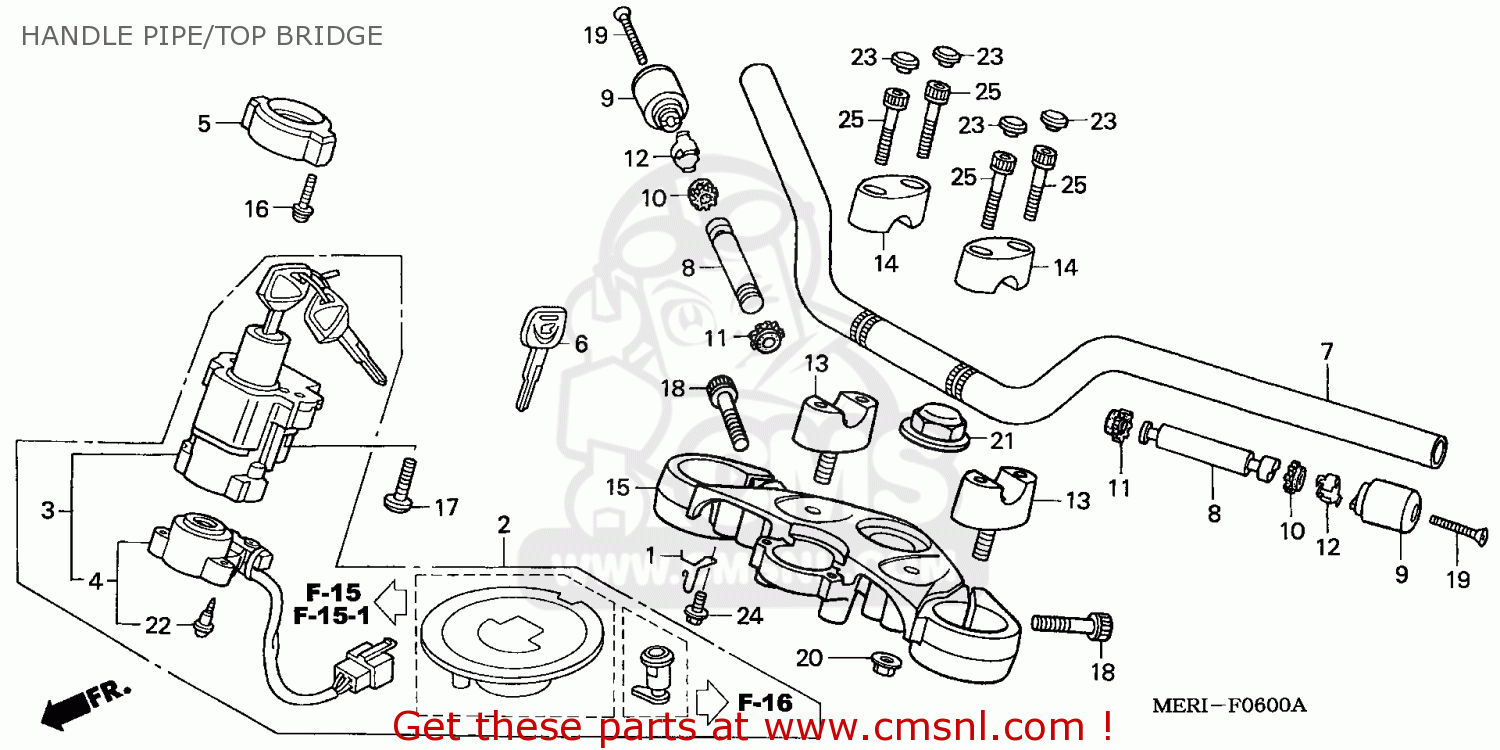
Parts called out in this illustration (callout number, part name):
2	KEY SET
3	SWITCH ASSY,COMB&
4	BASE COMP,CONTACT
5	COVER COMB SW
6	KEY,COMP NO.1
7	PIPE,STRG.HANDLE
8	WEIGHT B,STRG.HND
9	WEIGHT,STRG HNDL
10	RUBBER A,HANDLE W
11	RUBBER A,HANDLE W
12	RING,HANDLE WEIGH
13	HOLDER COMP,HNDL
14	HOLDER ,(HANDLE P
15	BRIDGE,FORK TOP
16	SCREW-WASH.,5X22
17	BOLT,ONE-WAY 8MM
18	BOLT,SOCKET,8X27
19	SCREW,OVAL,6X50
20	NUT,U,FLANGE,10MM
21	FLANGE NUT,STEERI
22	SCREW,TAPPING,3X1
23	CAP,SOC.BOLT 8MM
25	SOCKET BOLT,8X32
